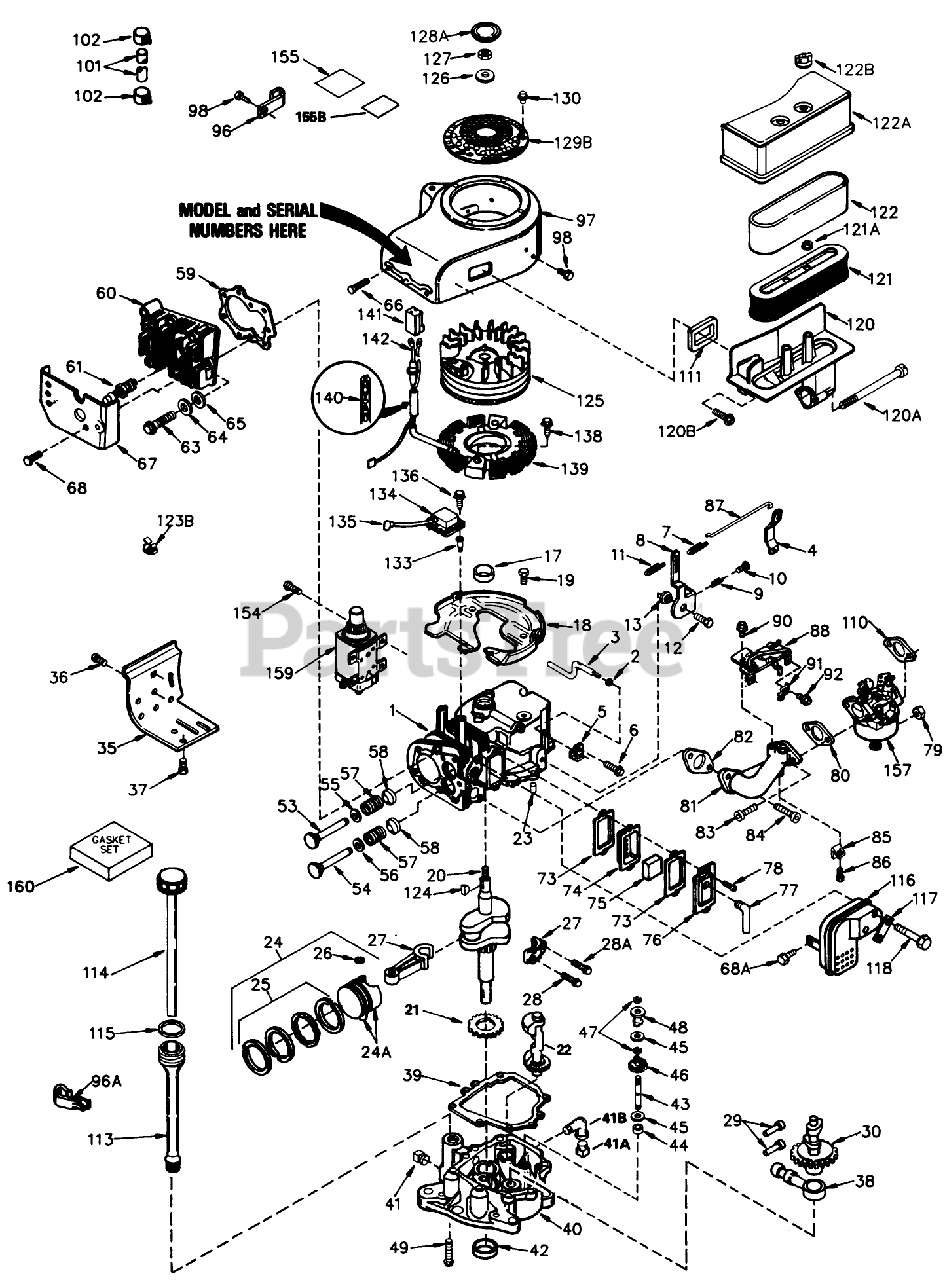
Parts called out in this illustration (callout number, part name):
1	Cylinder Assy. (Incl. Ref. #17 23)
2	Washer, Flat
3	Rod, Governor
4	Governor Lever
5	Clamp-Lever, Governor
6	Screw
7	Spring, Extension
8	Lever, Control (Incl. Ref. #11, 12, 13 110)
9	61709/GIL1515A/95-5
10	Screw
11	Spring, Control
12	SCREW, HEX WASHER HD.
13	Bell crank
17	Seal-Oil
18	Baffle-Blower Housing
19	Screw (1/4-20x19/32)
20	Crankshaft
21	Counterbalance Gear
22	Weight Assy.,Counter balance
23	Pin-Dowel
24	Piston, Pin Ring Assy.(Std.) (Incl. Ref. #24A, 25 26)
24	Piston, Pin Ring Assy. (.010 oversize) (Incl. Ref. #24A, 25 26)
24	Piston, Pin Ring Assy. (.020 oversize) (Incl. Ref. #24A, 25 26)
24A	Piston Pin Assy. (Std.) (Incl. Ref. #26)
24A	Piston Pin Assy. (.010 oversize) (Incl. Ref. #26)
24A	Piston Pin Assy. (.020 oversize) (Incl. Ref. #26)
25	Ring Set (Std.)
25	Ring Set (.010" OS)
25	Ring Set (.020" OS)
26	Ring, Piston Pin Retaining
27	Rod Assy., Connecting (Incl. Ref. #28 28A)
28	Bolt-Rod
28A	Bolt-Rod
29	Lifter, Valve
30	Camshaft (Mechanical Compression Release)
35	Extension-Housing, Blower
36	Screw
37	Screw
38	Pump, Oil
39	Gasket, Mounting Flange
40	Flange Assy., Mounting (Incl. Ref.#41, 41A, 42, 43 45)
41	Plug, Drain
41A	Plug, Oil drain
41B	Elbow, 90 Degrees (Can be purchased locally)
42	Seal-Oil
43	Shaft, Governor
44	Spacer Assy. Governor (Incl. Ref. #41)
45	Washer-Flat
46	Gear Assy., Governor (Incl. Ref. #45)
47	Ring-Retaining
48	Spool-Governor
49	Screw (1/4-20x1-3/16)
53	Valve, Exhaust (Standard)(Incl. No. 9)
53	Valve, Exhaust (1/32" oversize)(Incl. No. 9)
54	Valve, Intake (Std.) (Incl. Ref. #58)
54	Valve, Intake (1/32" oversize) (Incl. Ref. #58)
55	Cap-Spring, Valve
56	Seal-Intake Valve
57	Spring-Valve
58	Keeper-Spring, Valve
59	Gasket-Cylinder Head
60	Head Cylinder
61	Plug, Spark (Champion RCJ-8)
63	Screw (5/16-18 X 2)
64	Washer-Belleville
65	Washer-Flat
66	Screw (5/16-18x3/4)
67	Cover-Cylinder Head
68	Screw (1/4-20 X 5/8)
68A	Screw (1/2-20x5/8)
73	Gasket-Cover, Valve
74	Body-Breather
75	Element-Breather
76	Cover-Valve
77	Tube-Breather
78	Screw
79	Nut and Lock Washer (1/4-28)
80	Gasket, Carburetor
81	Pipe, Intake
82	Gasket-Pipe, Intake
83	Screw (1/4-28x1)
84	Screw (T-30, 5/16-18x1-3/32)
85	Bracket, Intake Pipe
86	Screw (1/4-20 X 5/8)
87	Link, Throttle
88	Bracket Assy., Control
90	Screw (10-24 x 9/16)
91	Conduit
92	Screw (10-32 x 3/8)
96	Clip Oil Tube
96A	Clip, Oil fill tube
97	Housing, Blower
98	Screw
101	Line-Fuel
102	Clamp-Line, Fuel
110	Clutch Arm Assembly
111	Gasket, Blower Housing
113	Tube-Fill, Oil
114	Dipstick, Oil
115	O-Ring
116	Muffler Assy.
117	62513 SNWTHWR W/284
118	Screw, Hex Hd.
120	Body, Air Cleaner
120A	Screw, Fil. Hd.
120B	Screw, Hex Washer Hd. Self-drill, Self-tap
121	Element, Air Cleaner (Incl. Ref. #121A)
121A	Nut Lockwasher
122	Filter, Poly Pre-cleaner
122A	Cover, Air Cleaner
122B	Nut, Wing
123B	51004 GIL ROTARY TI
124	Key-Flywheel
125	Flywheel ASM
126	Washer-Belleville
127	Nut-Flywheel
128A	Plug, Screen
129B	Screen, Starter
130	Pop Rivet (Can be purchased locally)
134	Solid State ASM
135	Cover-Spark Plug
136	Screw
138	Screw (1/4-20 x 3/4)
139	Coil Assy., Alternator (3 Amp D.C.) (Incl. Ref. #140, 141 142)
140	Diode
141	Connector Body
142	Terminal-Female
154	Screw
155	Decal-Instruction
155B	Decal, Instruction
157	Carburetor (Incl. Ref. #80)
159	Pin
160	Gasket Set (Incl. items marked *)
